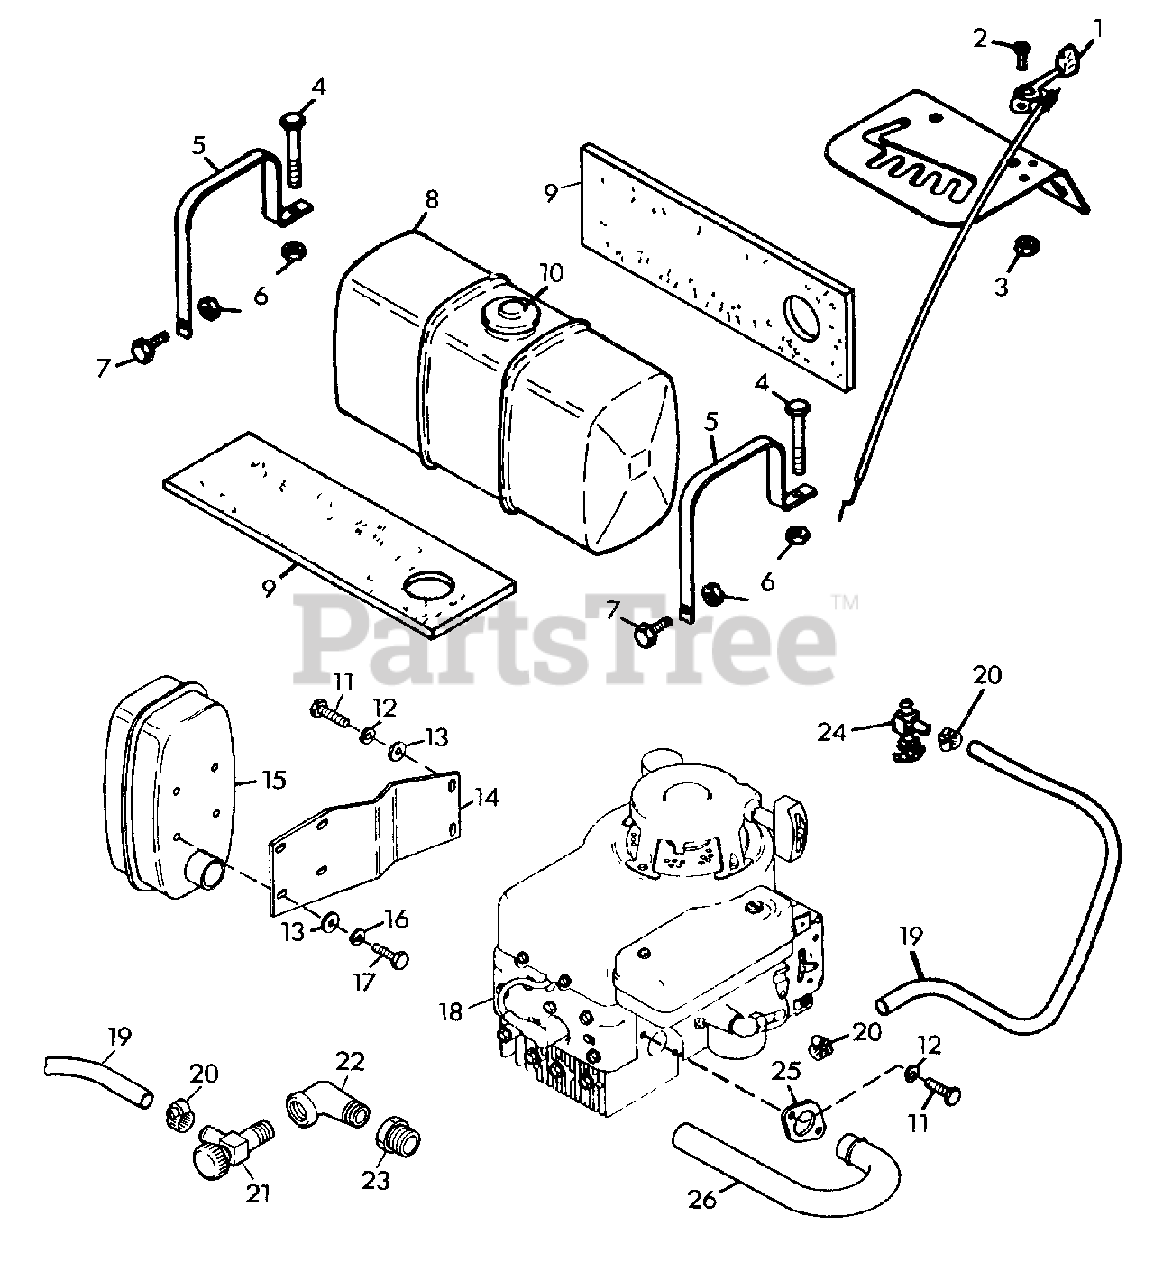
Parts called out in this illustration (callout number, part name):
1	LEVER, THROTTLE CONTROL
2	SCREW, MACH. 10-24X.50 PHD
3	NUT, LOCK 10-24
4	BOLT, HEX 1/4-20X1.75
5	STRAP, FUEL TANK
6	NUT, LOCK 1/4-20
7	BOLT, HEX 1/4-20X.625
8	TANK, FUEL (12 QTS.)
9	PAD, GAS TANK
10	CAP, GAS TANK
11	BOLT, HEX 5/16-18X.75
12	WASHER, LOCK 5/16 REG.
13	WASHER, FLAT .344X.688X.065
14	PLATE, EXHAUST
15	MUFFLER, 11 H.P. B & S
16	WASHER, LOCK 1/4 REG.
17	BOLT, HEX 1/4-20X.75
18	ENGINE, 12 H.P. B&S
19	HOSE, FUEL
20	CLAMP, HOSE
21	COCK, OIL DRAIN
22	EL, 90 DEG. STREET 1/4 NPT
23	ADAPTOR, OIL DRAIN
24	VALVE AND STRAINER
25	FLANGE, MUFFLER
26	TUBE, EXHAUST
